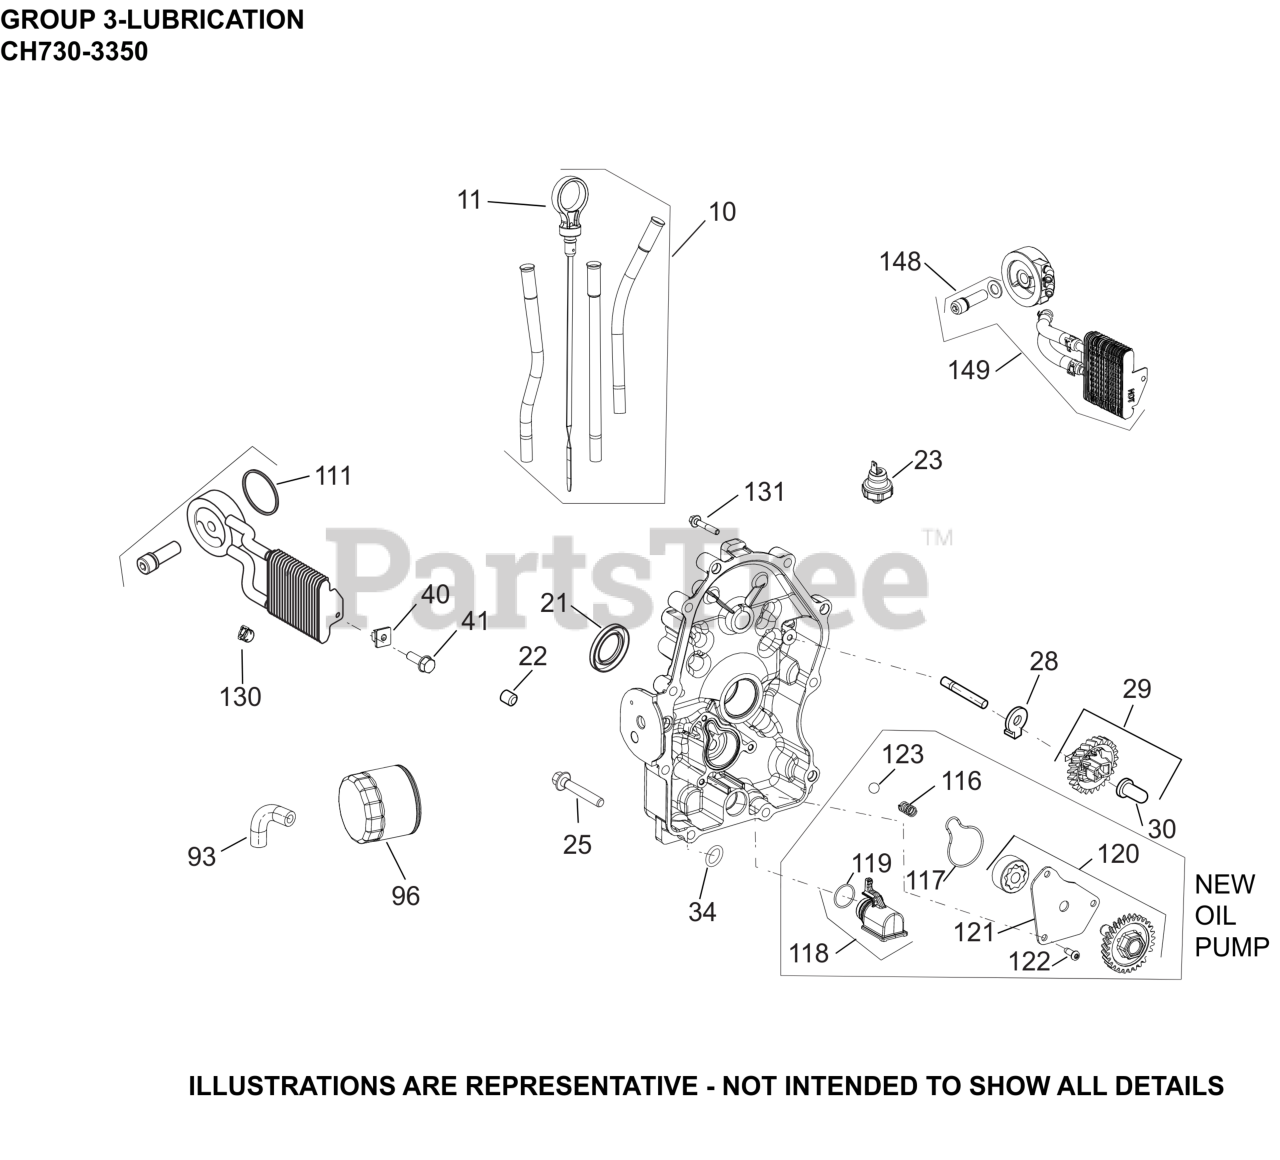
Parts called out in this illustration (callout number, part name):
10	KIT, DIPSTICK/DIPSTICK TUBES
22	PLUG, CTSK PIPE 1/8"
23	SENSOR, OIL PSI
25	SCREW, FLG M8X1.25X45
28	TAB, LOCKING
29	KIT, GOVERNOR GEAR W/PIN
30	PIN, GOVERNOR REGULATING
40	NUT, PLASTIC - BLACK
41	SCREW, HEX HEAD
93	KIT, HOSE 140MM
96	OIL FILTER
111	O-RING, OIL COOLER
116	SPRING, COMPRESSION
117	SEAL, OIL PUMP COVER
118	PICK-UP ASSEMBLY, OIL
119	O-RING, OIL PICK-UP
120	PUMP ASSEMBLY, OIL
121	COVER, OIL PUMP
122	SCREW, BUTTON HEAD
123	PRESSURE RELIEF BALL
130	CLAMP, HOSE LOW PROFILE
131	SCREW, HEX FLANGE
148	KIT, OIL FILTER NIPPLE
149	KIT, OIL COOLER
NI	KIT, CLOSURE PLATE ASSY
NI	SHAFT, GOVERNOR GEAR
NI	WASHER, FLAT
